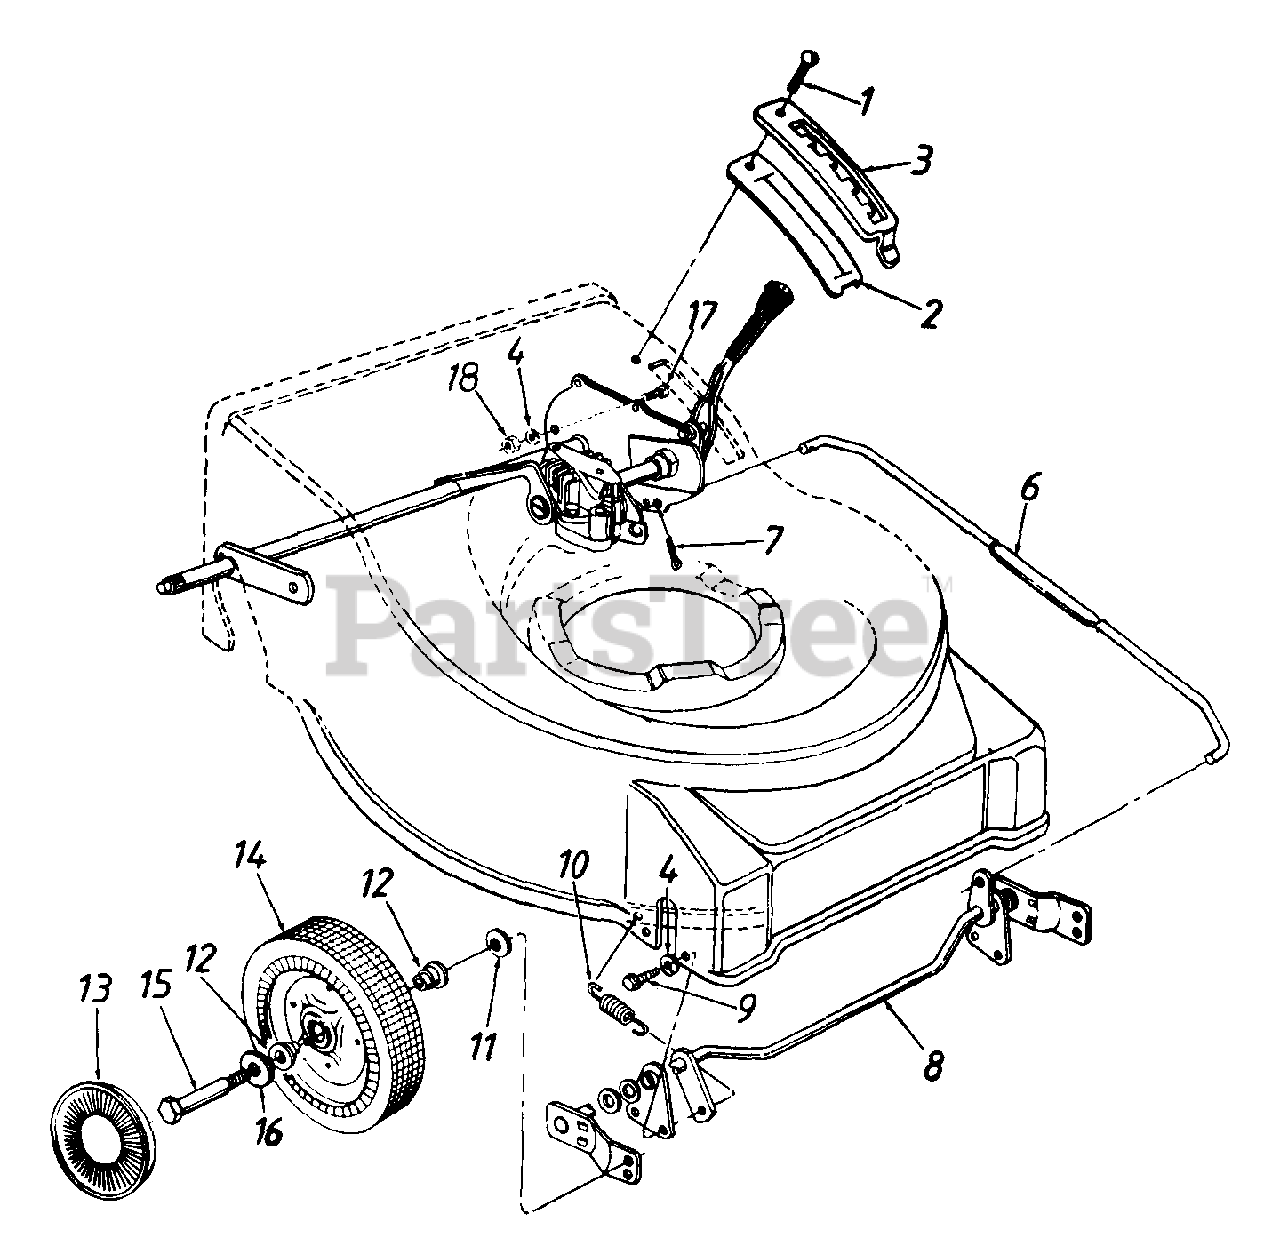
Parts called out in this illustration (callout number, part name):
1	Torx Mach. AB-Tap Scr. 1/4 x .62" Lg.
2	Height Adjustment Support
3	Height Adjustment Plate
4	L-Wash. 1/4" I.D.
6	Height Adj. Connecting Rod
7	Cotter Pin 3/32" Dia.
9	Hex L-Wash. Hd. AB-Tap Scr. 1/4 x .38" Lg.
10	Extension Spring 2.39" Lg.
11	Bell-Wash. .380" I.D. x .88"
12	Ball Bearing 1/2" I.D.
13	Hub Cap
14	Wheel Ass'y. Comp. - Front
15	Shld. Bolt .498" Dia. x 1.45"
16	Wave Wash. .51" I.D. x .78"
17	Mach. Scr. 1/4 - 20 x .5" Lg.
18	Hex Jam Nut 1/4 - 20 Thd.
